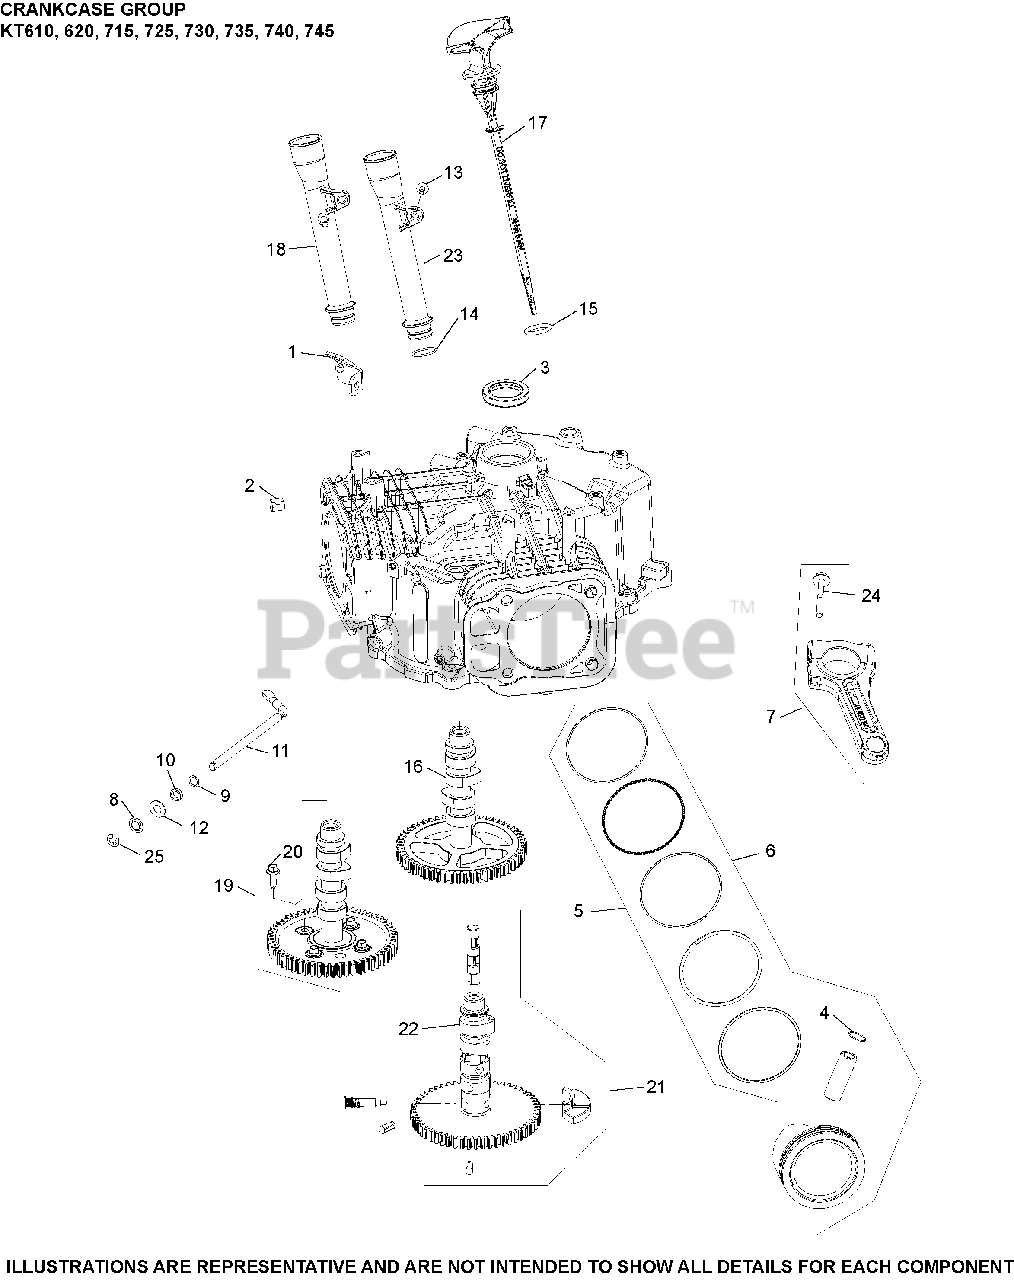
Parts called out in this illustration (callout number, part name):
1	BRACKET, OIL FILL TUBE
2	PIN, LOCATING
3	SEAL, OIL (HELIX LIP)
4	RETAINER, PISTON PIN
5	RING SET(STD)STYLE B-1.2mm Tp RING THICK
5	RING SET(.08)STYLE B-1.2mm Tp RING THICK
5	RING SET(.25)STYLE B-1.2mm Tp RING THICK
5	RING SET(.50)STYLE B-1.2mm Tp RING THICK
6	PISTON W/RINGS (STYLE B)(STD) - RING SET 25 108 01-S
6	PISTON W/RINGS (STYLE B)( 0.08) - RING SET 25 108 02-S
6	PISTON W/RINGS (STYLE B)(0.25) - RING SET 25 108 03-S
6	PISTON W/RINGS (STYLE B)(0.50) - RING SET 25 108 04-S
7	ROD, ASSY CONNECTING (STD)-(#2406730S)
7	ROD ASSY, CONNECTING U/S (.010”) (.25 mm) -USE 24 067 31-S
9	WASHER, FLAT 11/32"
10	SEAL, GOVERNOR CROSS SHAFT
12	WASHER, FLAT 9 MM
16	CAMSHAFT ASSEMBLY (PLASTIC GEAR)
17	DIPSTICK, ASSEMBLY
18	TUBE ASSEMBLY, OIL FILL
